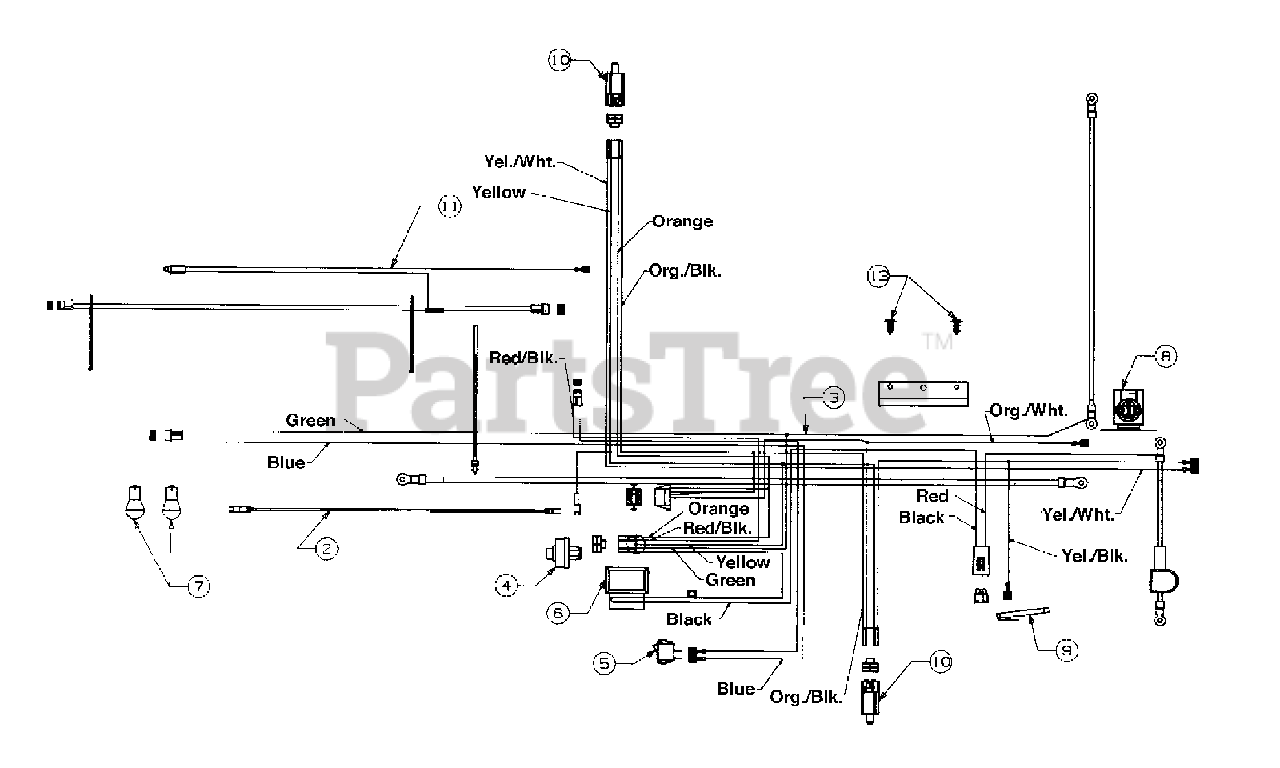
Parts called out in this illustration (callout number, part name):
2	Harness Adapter
3	Wire Harness w/Light Switch & Amp
4	Ignition Switch
5	Light Switch
6	Ammeter
7	Bulb
8	Solenoid
9	Safety Switch (Reverse)
10	Safety Switch
11	Harness Adapter (Alt.)
13	Ratchet
